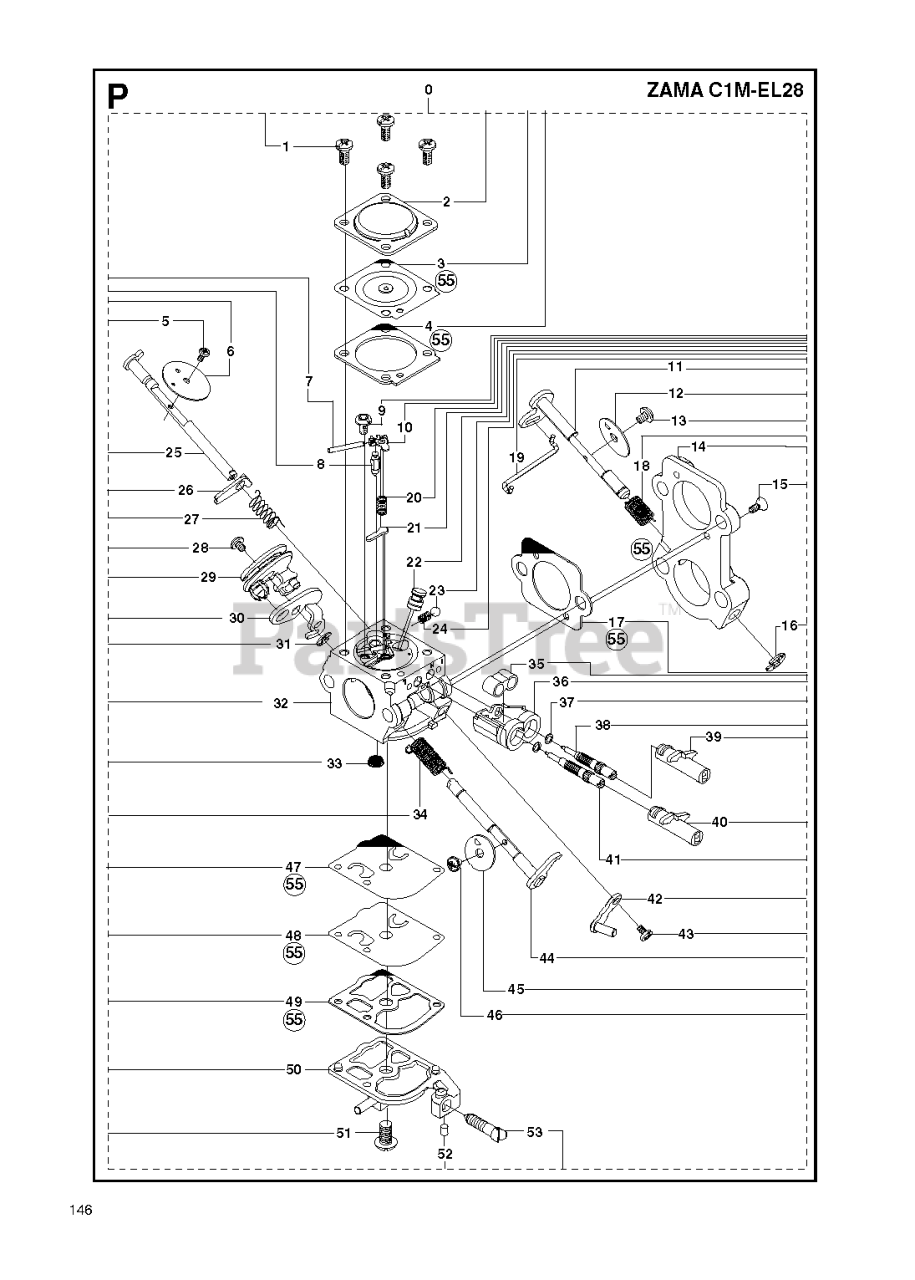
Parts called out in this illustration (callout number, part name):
3	DIAPHRAGM
6	CHOKE FLAP
7	PIN FULCRUM
8	INLET NEEDLE
12	THROTTLE FLAP
14	RP CARBURETOR
25	CHOKE SHAFT
32	RP CARBURETOR
33	STRAINER
38	NEEDLE HIGH SPEED
41	LOW SPEED NEEDLE
44	THROTTLE SHAFT
47	PUMP DIAPHRAGM
48	DIAPHRAGM
55	GASKET SET
